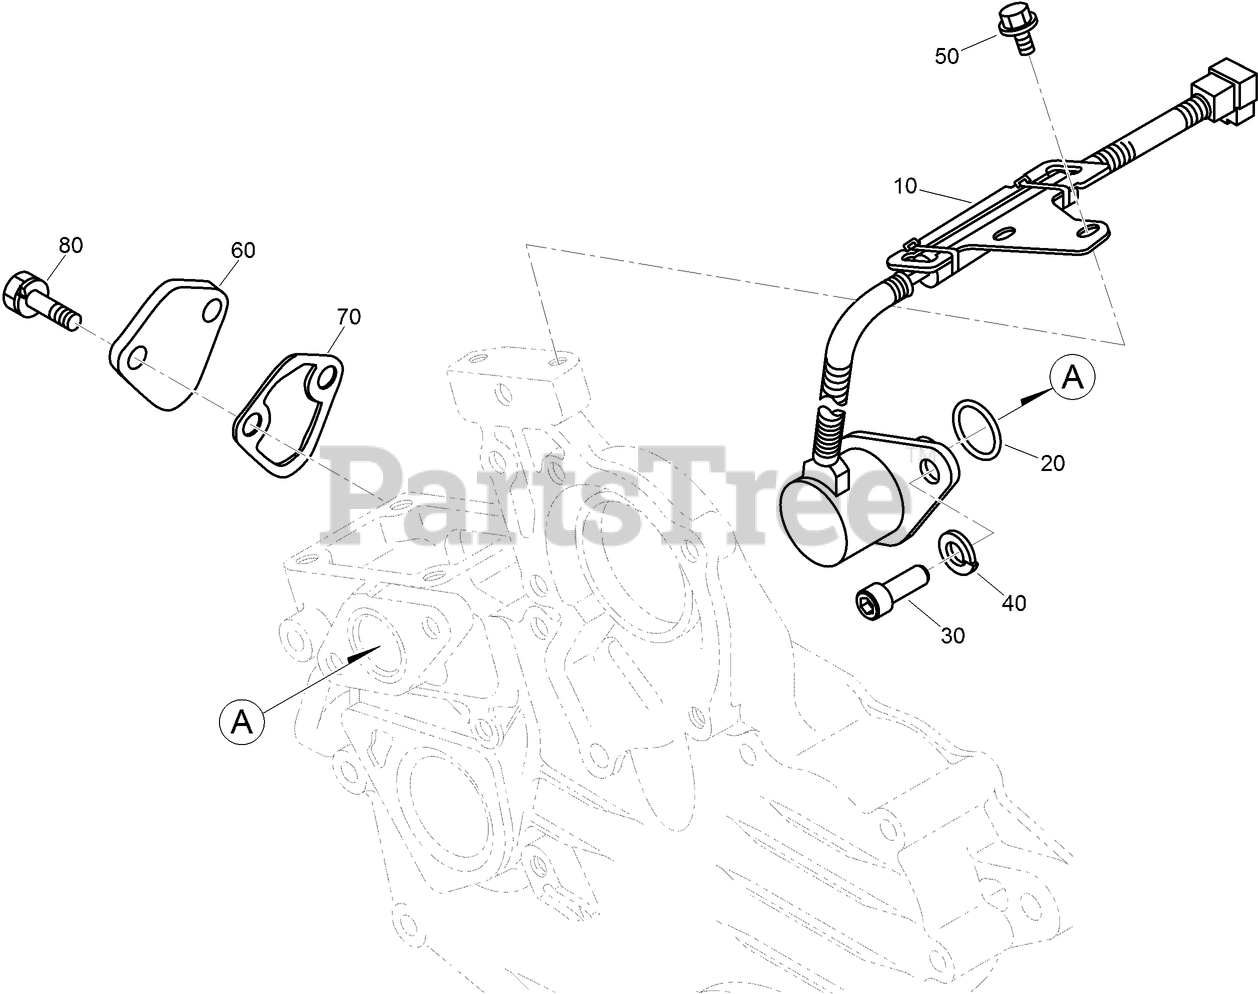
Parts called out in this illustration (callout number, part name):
10	SOLENOID STOP ASM
20	O-RING
30	BOLT-HSH
40	WASHER-SPRING
50	BOLT-FLANGE
60	COVER
70	GASKET-PUMP, FUEL
